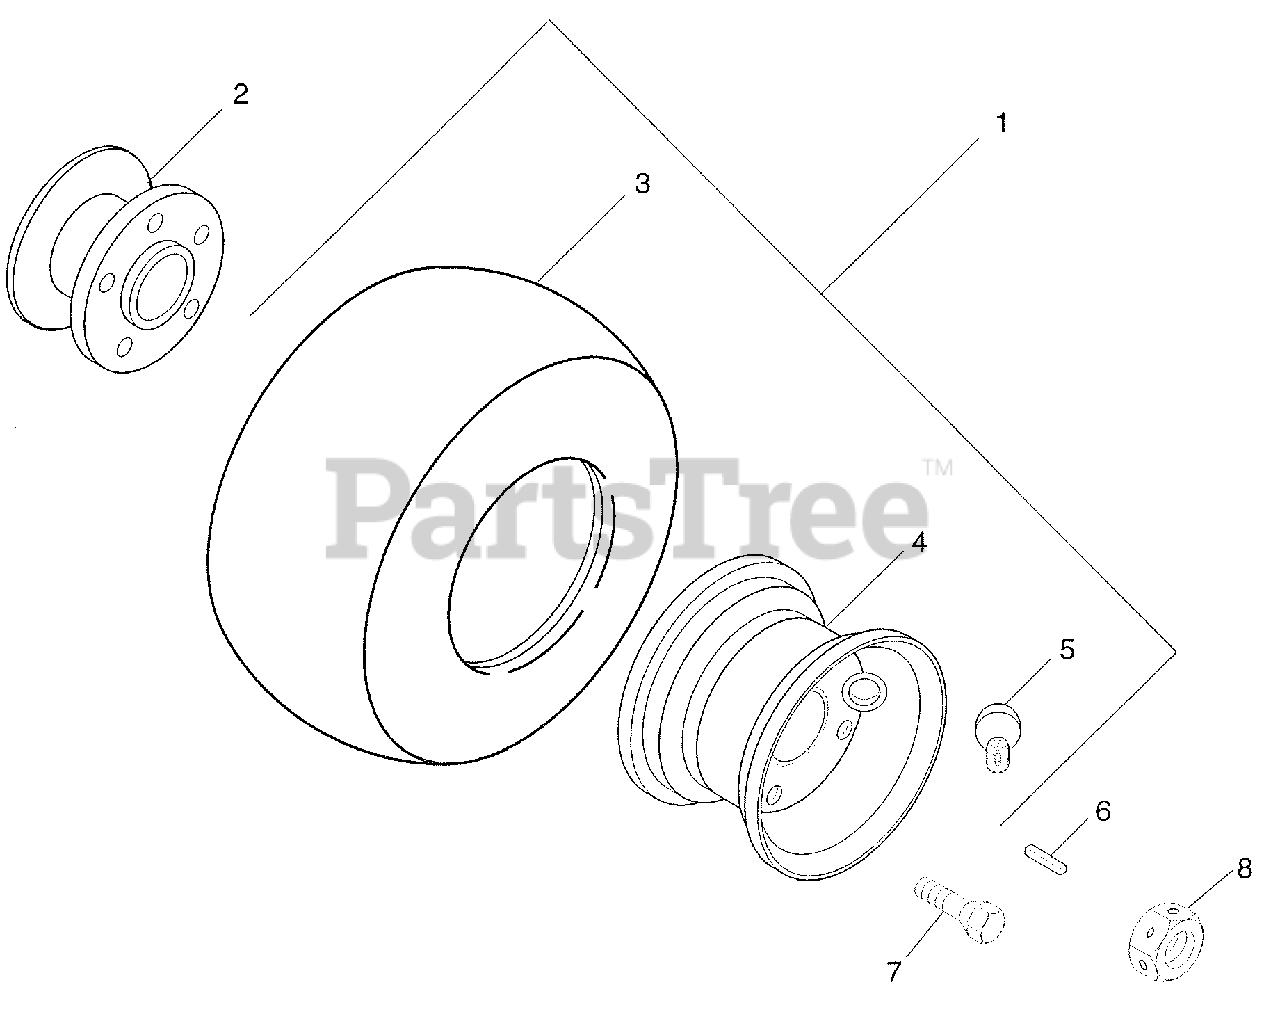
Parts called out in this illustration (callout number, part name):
1	Tire/Wheel Assembly 20 X 10-10
2	Hub, Disc Brake
3	Tire 20 X 10.00-10 Turf Trac RS
4	Wheel, 10.00 X 7.75
5	Valve Stem Assembly
6	Key, Rectifier .313 X .275 X .932
7	Bolt .44-20 X 1.0
8	Nut Pack 1.00-20
